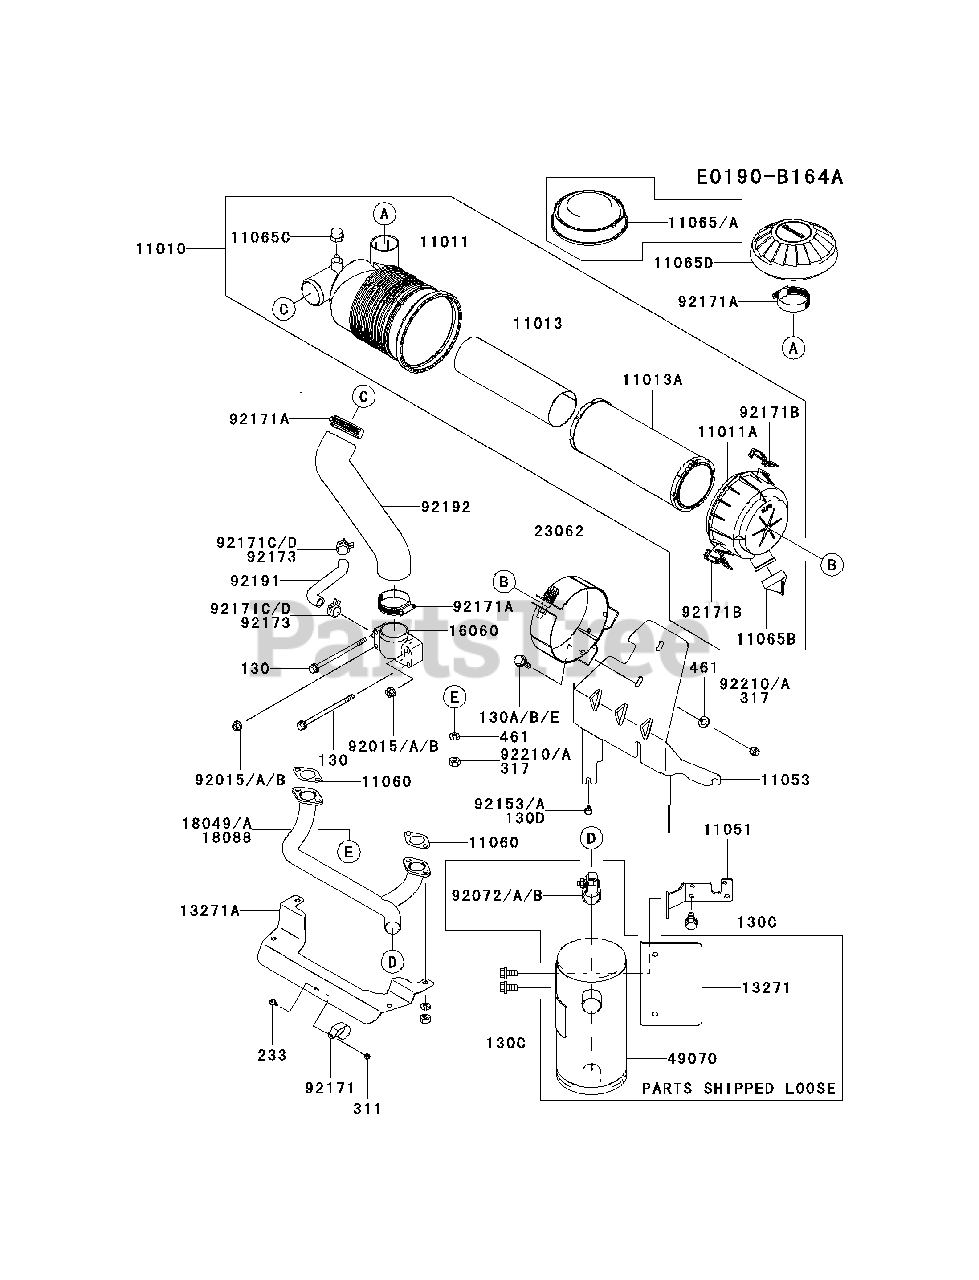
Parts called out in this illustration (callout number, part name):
130	BOLT-FLANGED,6X105
130A	BOLT-FLANGED,8X14
130C	BOLT-FLANGED,8X16
233	SCREW-PAN-WP+-,4X16
311	NUT-HEX,4MM
461	WASHER-SPRING,8MM
